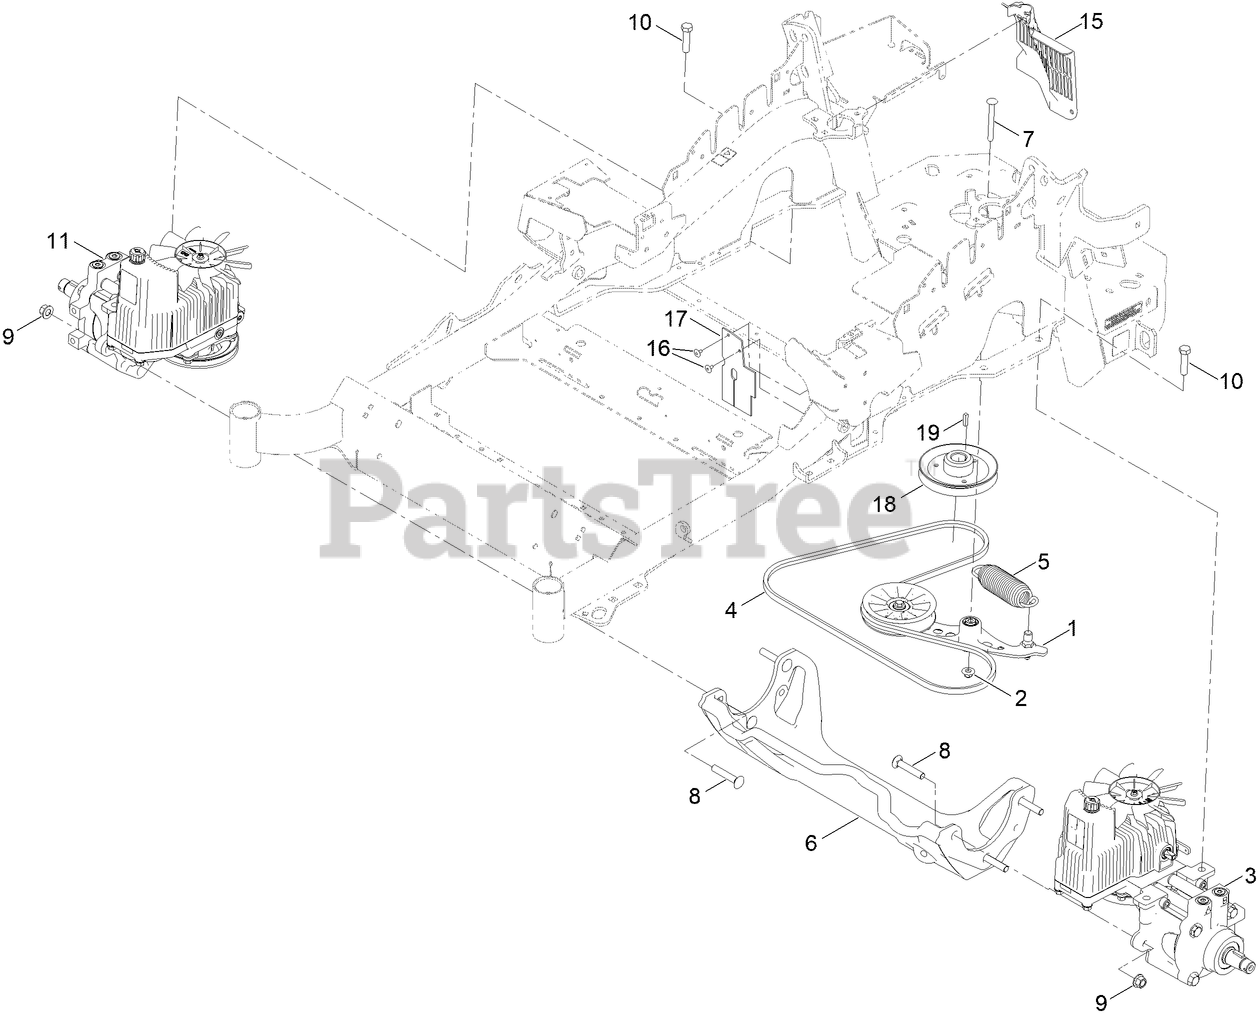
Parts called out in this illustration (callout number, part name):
1	PUMP IDLER ASM
2	NUT-FLANGE, NI
3	HYDRO-LH
4	BELT-V
5	SPRING-EXTENSION
6	CRADLE-HYDRO
7	BOLT-SHOULDER, CARRIAGE
8	SCREW-CARR
9	NUT-LOCK
10	SCREW-HH
11	HYDRO-RH
15	GUARD-HYDRO, REAR (RH)
16	RIVET-POP
17	DEFLECTOR-AIR FLOW
18	SHEAVE, W/HUB
